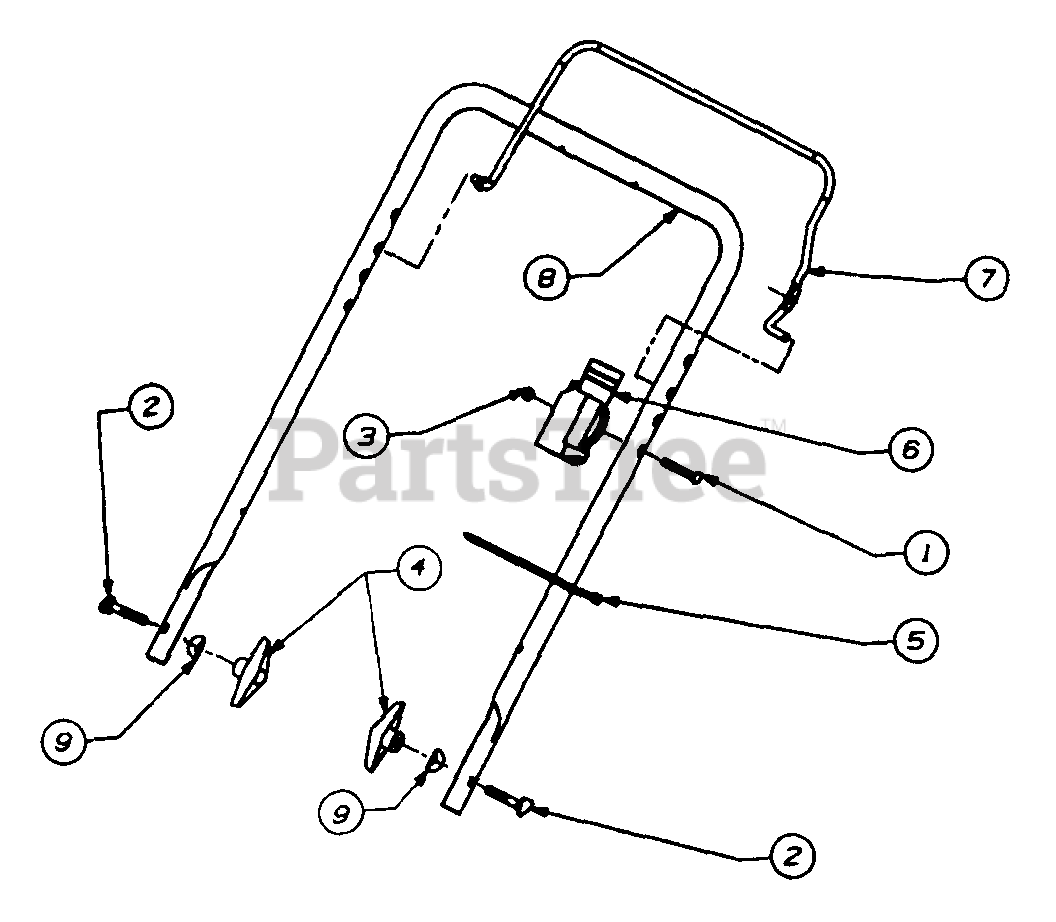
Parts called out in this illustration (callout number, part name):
1	Oval C-Sink L Screw
2	Bolt Carriage
3	Nut Insl. Lock
4	Knob - Handle
5	Tie Cable
6	Control Lever Body
